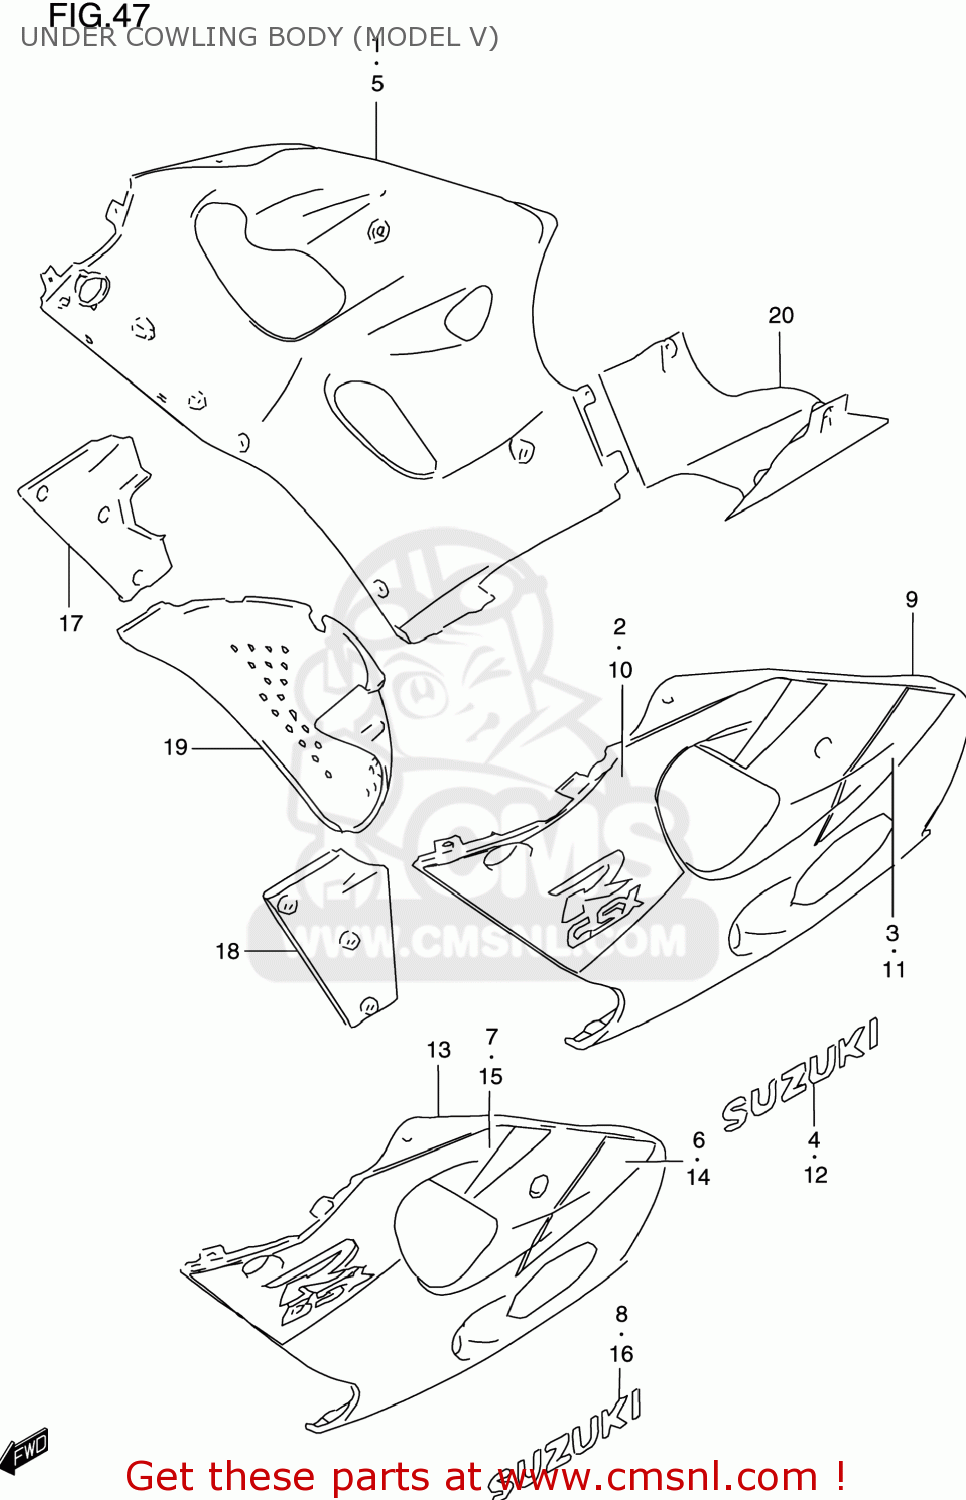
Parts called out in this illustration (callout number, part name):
1	COWLING ASSEMBLY,UNDER,RIGHT
2	TAPE SET,UNDER COWLING,R
3	TAPE,COWL UNDER LWR,R
4	EMBLEM,SUZUKI(SILVER)
5	COWLING ASSY,UNDER,R
6	TAPE,COWL UNDER LWR,R
7	TAPE SET,UNDER COWLING,R
8	EMBLEM,SUZUKI(WHITE)
9	COWLING ASSY,UNDER,L
10	TAPE SET,UNDER COWLING,L
11	TAPE,COWL UNDER LWR,L
12	EMBLEM,SUZUKI(SILVER)
13	COWLING ASSEMBLY,UNDER,LEFT
14	TAPE,COWL UNDER LWR,L
15	TAPE SET,UNDER COWLING,L
16	EMBLEM,SUZUKI(WHITE)
17	COWLING,UNDER INNER,R
18	COWLING,UNDER,INNER,LEFT
19	COWLING,UNDER,CENTER
20	COWLING ASSEMBLY,UNDER,REAR
